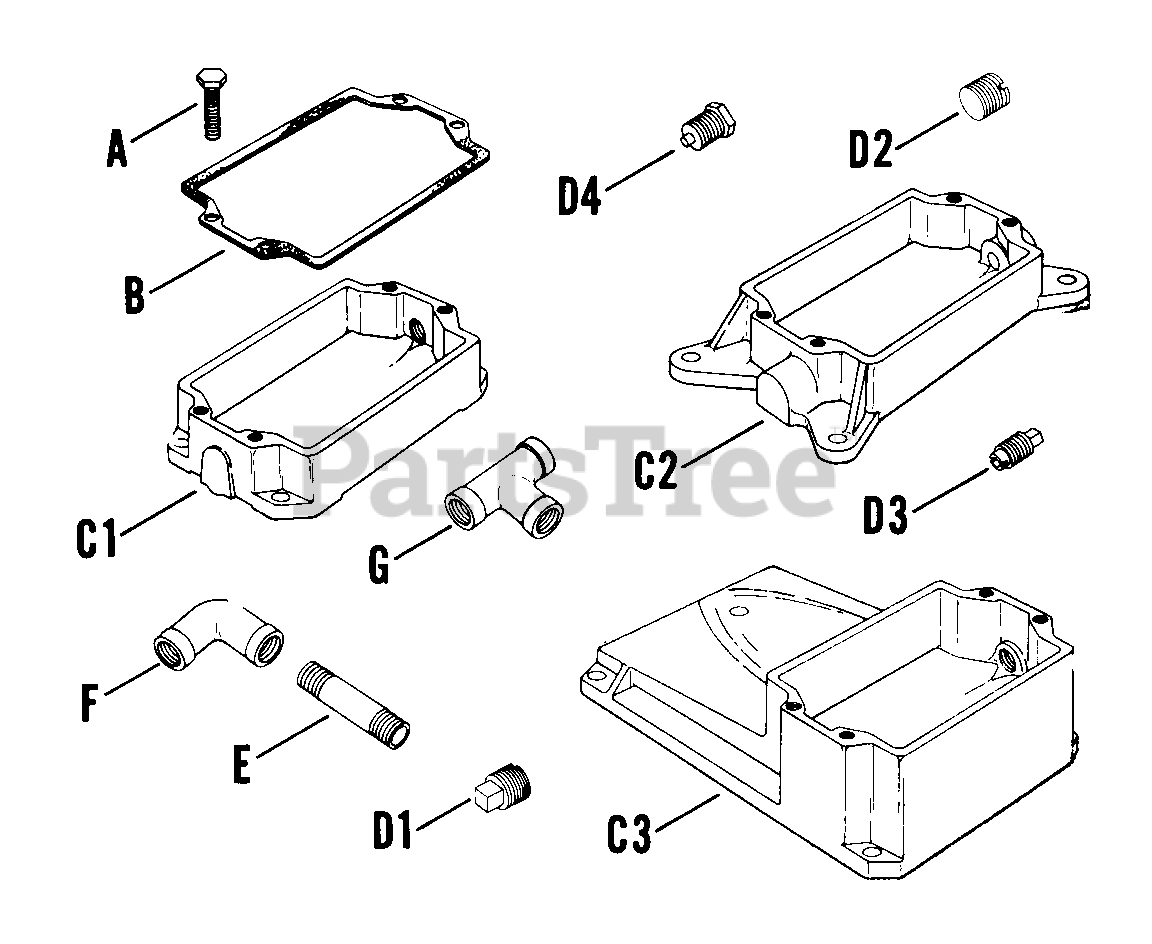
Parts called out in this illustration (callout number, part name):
B	GASKET - DISCONTINUED
C1	PAN - USE 46 199 01
D1	PLUG,PIPE 1/4 NPTF SQUARE HD USE 25 139 53-S
